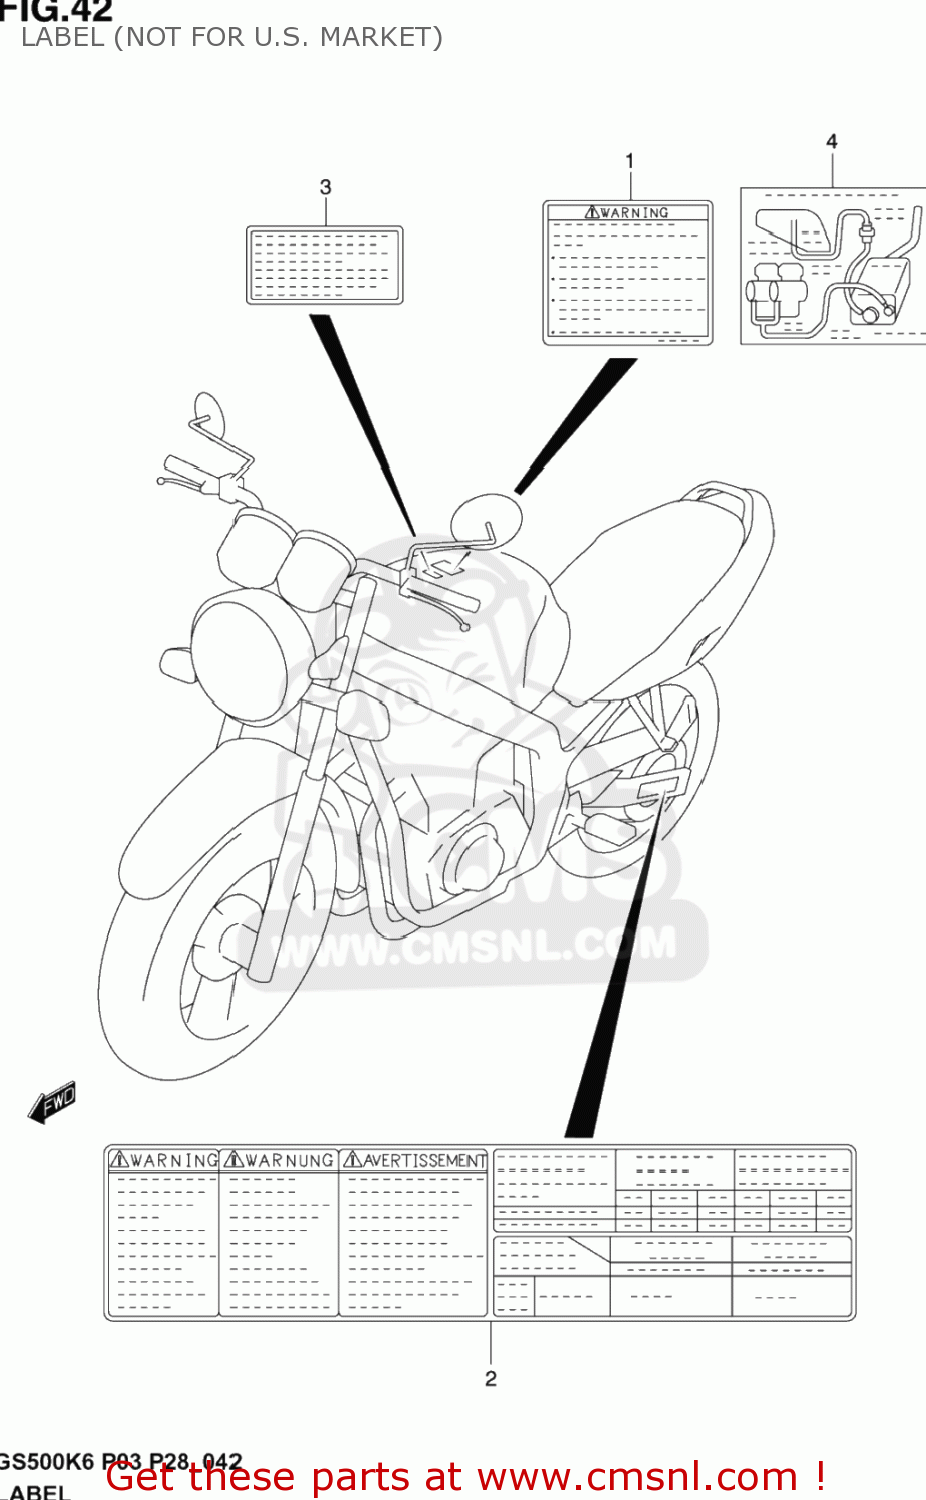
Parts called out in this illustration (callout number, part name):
1	LABEL,GENERAL WARNING
2	INDICATIELABEL
3	LABEL,MANUAL NOTICE
4	LABEL,VACUUM HOSE ROUTING
5	OM GS500H K3
